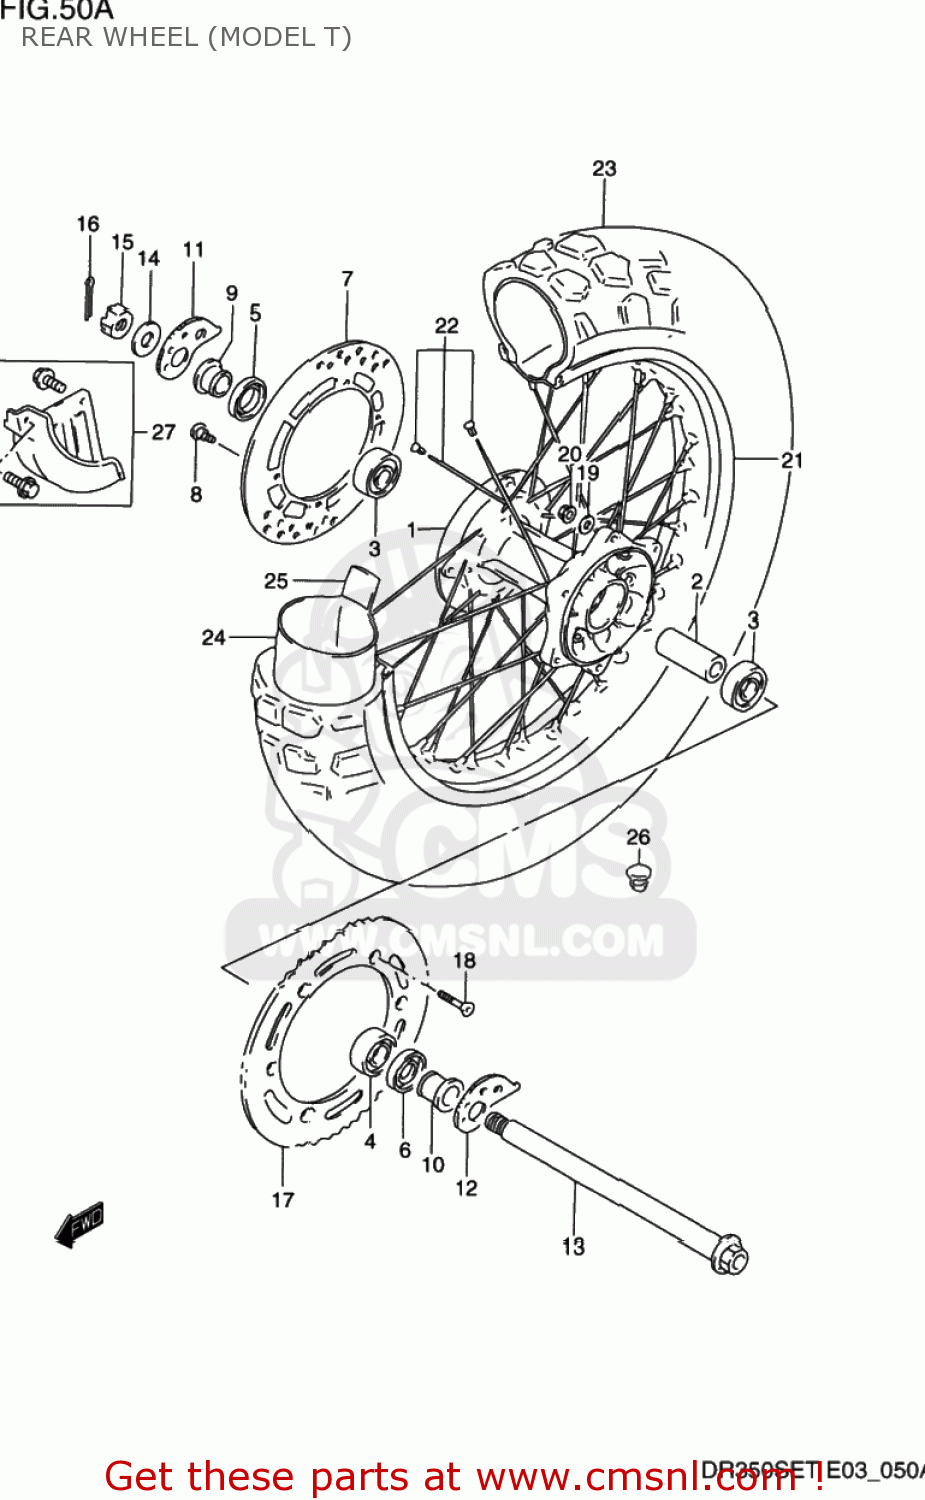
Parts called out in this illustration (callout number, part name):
1	HUB,RR WHEEL
2	SPACER,RR HUB BEARING
3	BALL BEARING
4	BEARING
5	SEAL,OIL(26X42X8)
6	SEAL,OIL(26X47X5)
7	DISC,RR BRAKE
8	BOLT,BRAKE DISC
9	SPACER,RR AXLE,R
10	SPACER,RR AXLE,L
11	ADJUSTER,CHAIN,R
12	ADJUSTER,CHAIN,L
13	AXLE,RR
14	WASHER(19X32X3.2)
15	NUT
16	PIN,COTTER
17	SPROCKET,RR(NT:41)
18	SCREW(8X33.5)
19	WASHER
20	NUT
21	RIM,REAR WHEEL (2.15X18)
22	SPOKE SET,RR WHEEL
23	TIRE,RR(110/90 18)
24	TUBE ASSEMBLY,WHEEL,INNER
25	PROTECTOR,WHL INR TUBE
26	CAP(OD:12)
27	COVER SET,RR BRAKE DISC
